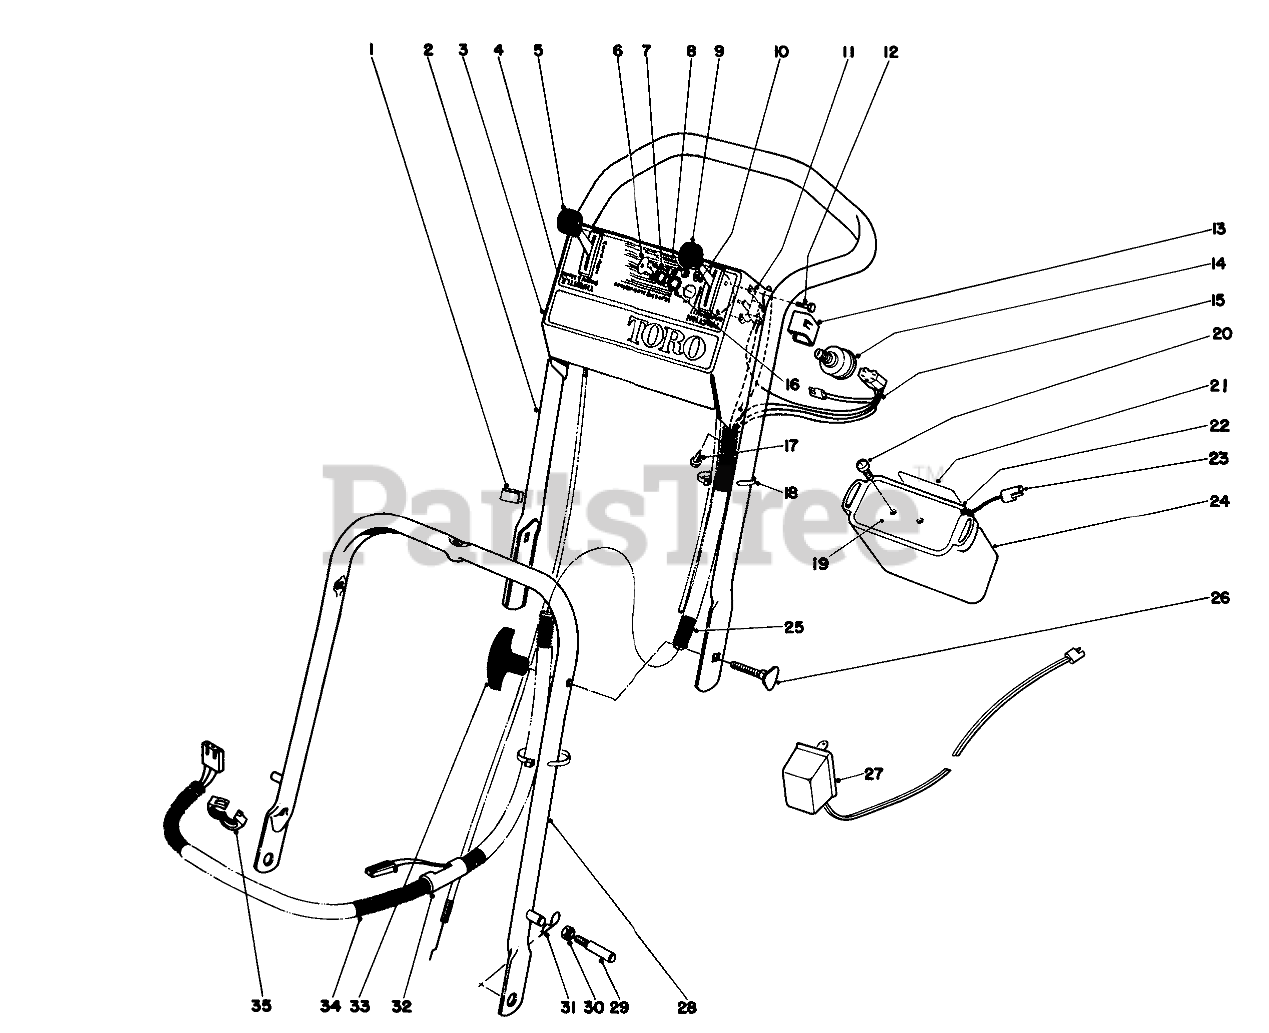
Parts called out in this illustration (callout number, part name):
2	UPPER HANDLE
3	Control Plate
4	Decal Control Plate
5	Control Throttle
8	NUT-HEX
9	Traction Control
10	WASHER-FLAT
11	CONTROL SWITCH
12	SCREW-HH
13	Cover Switch
14	SWITCH-STARTER
15	Wire Harness
16	WASHER-TOOTH, INTERNAL
17	SCREW-HWHTF
18	TIE-CABLE
19	BATTERY COVER
20	10-190X1/2 PAN HD SCR
21	Decal
22	Battery Assembly (Incl. Ref. #19-21 & 23-24)
23	Plug & Wire
24	Battery Case
25	Cover Wiring Harnes Upper
26	SCREW-HANDLE
27	Charger
28	Lower Handle
29	HANDLE PIN
30	Nut
31	PIN-COTTER, HAIR
32	Breakout Fitting
34	Cover Wiring Harness Lower
